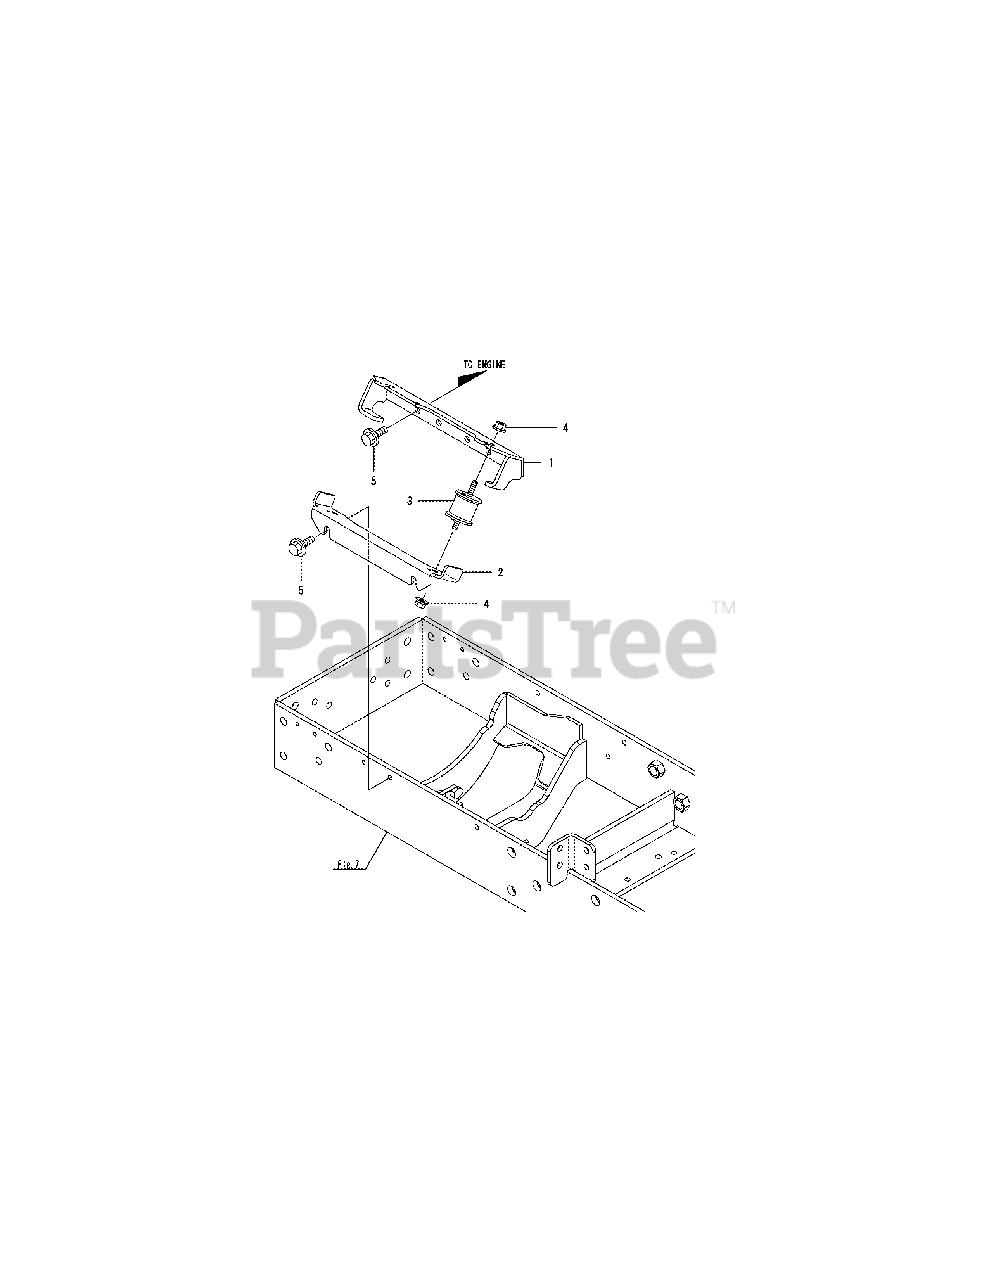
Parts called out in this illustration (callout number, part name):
1	Stay Assy, Engine
2	Stay, Mount Frame
4	Nut W/Washer 8
5	Bolt M10X 20 Plated
